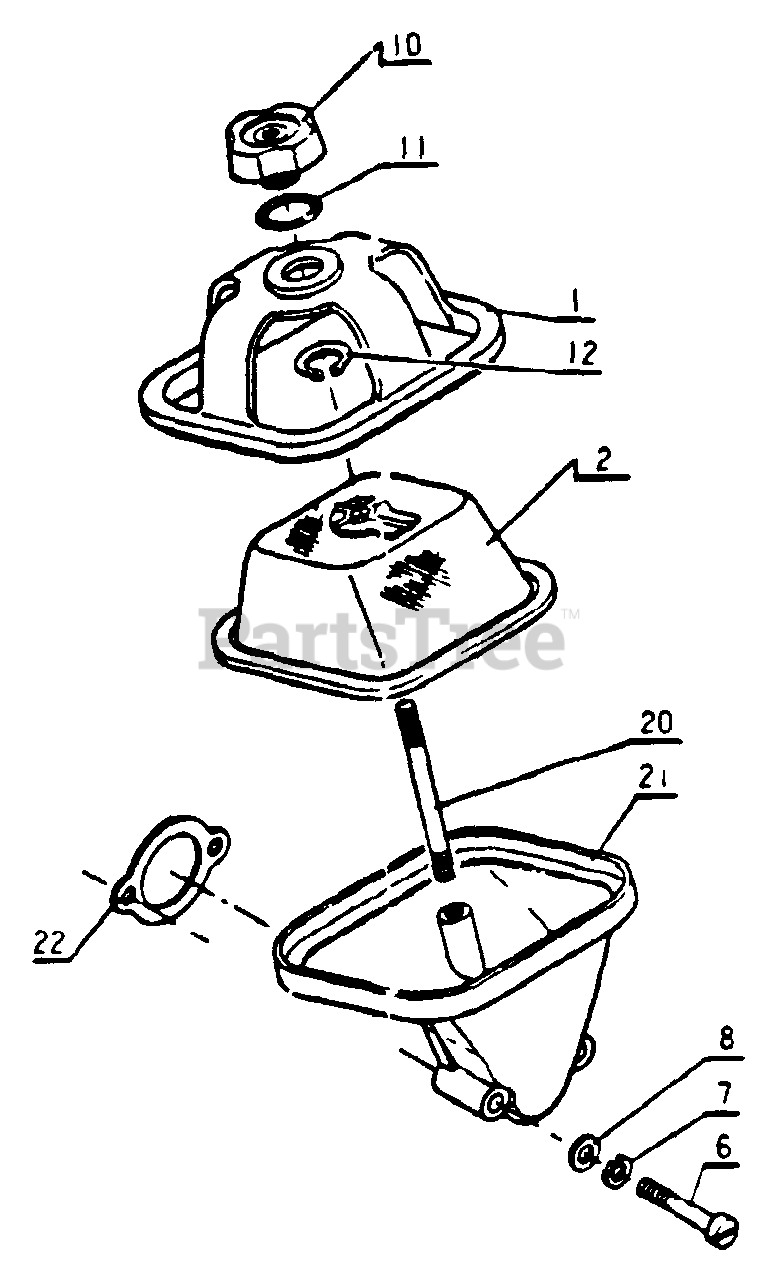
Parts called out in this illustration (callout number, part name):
1	COVER, AIR FILTER
2	FILTER, AIR
6	BOLT
7	WASHER, SPRING 5
8	WASHER, FLAT 5.5×10×0.8
10	WINGNUT
11	O-RING
12	E-RING
20	STUD
21	CASE, AIR FILTER
22	PACKING
